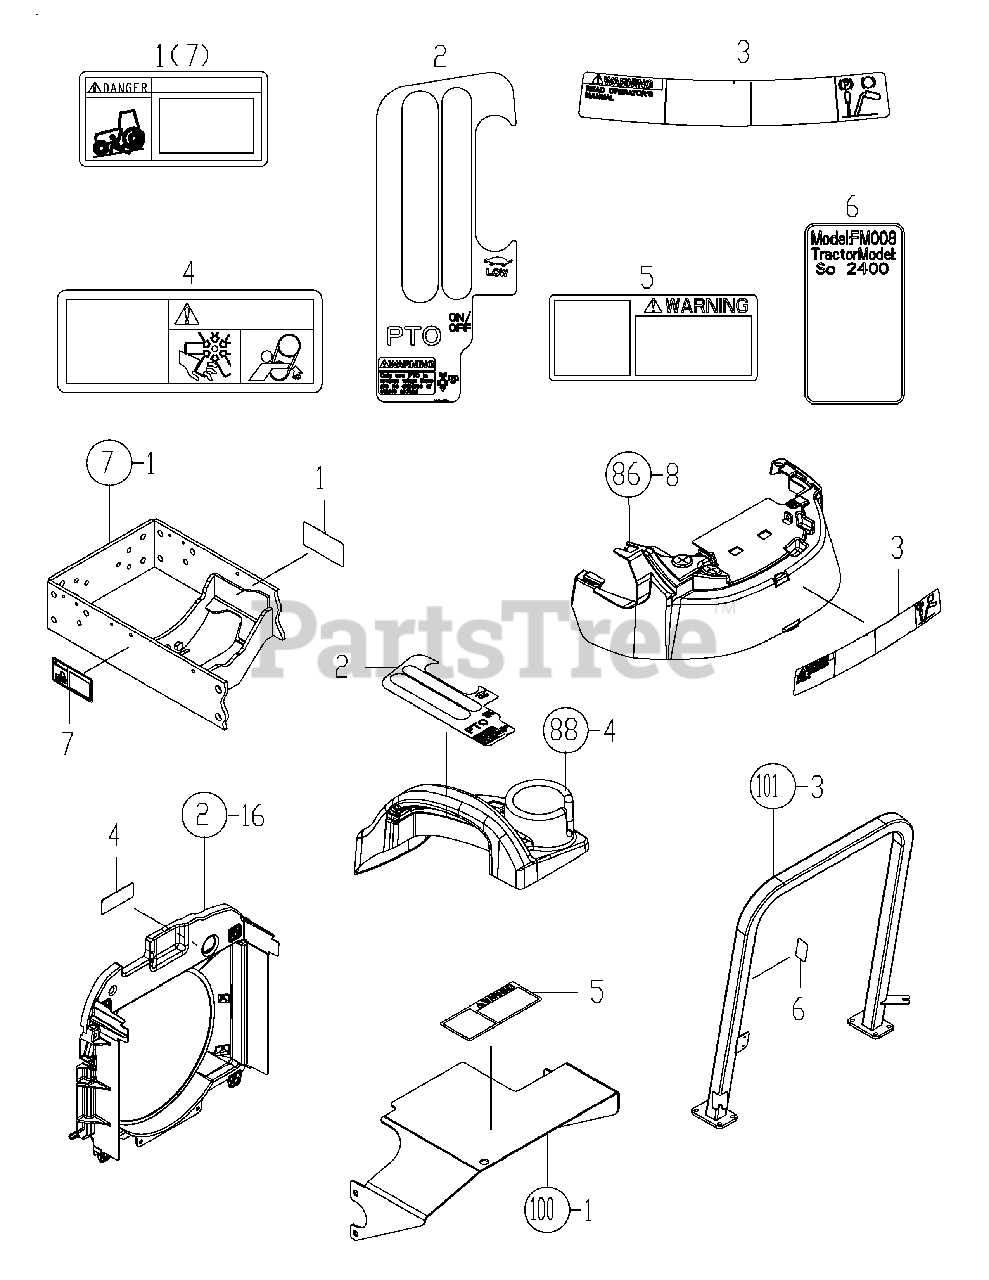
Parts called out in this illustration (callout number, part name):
1	LABEL,DANGER,START
2	LABEL, LEVERGUIDE L
3	LABEL,CAUTION,GENERAL
4	LABEL,WARNING,FAN
5	LABEL,PTO WARNING
6	LABEL,ROPS
7	LABEL, WARNING STOP
